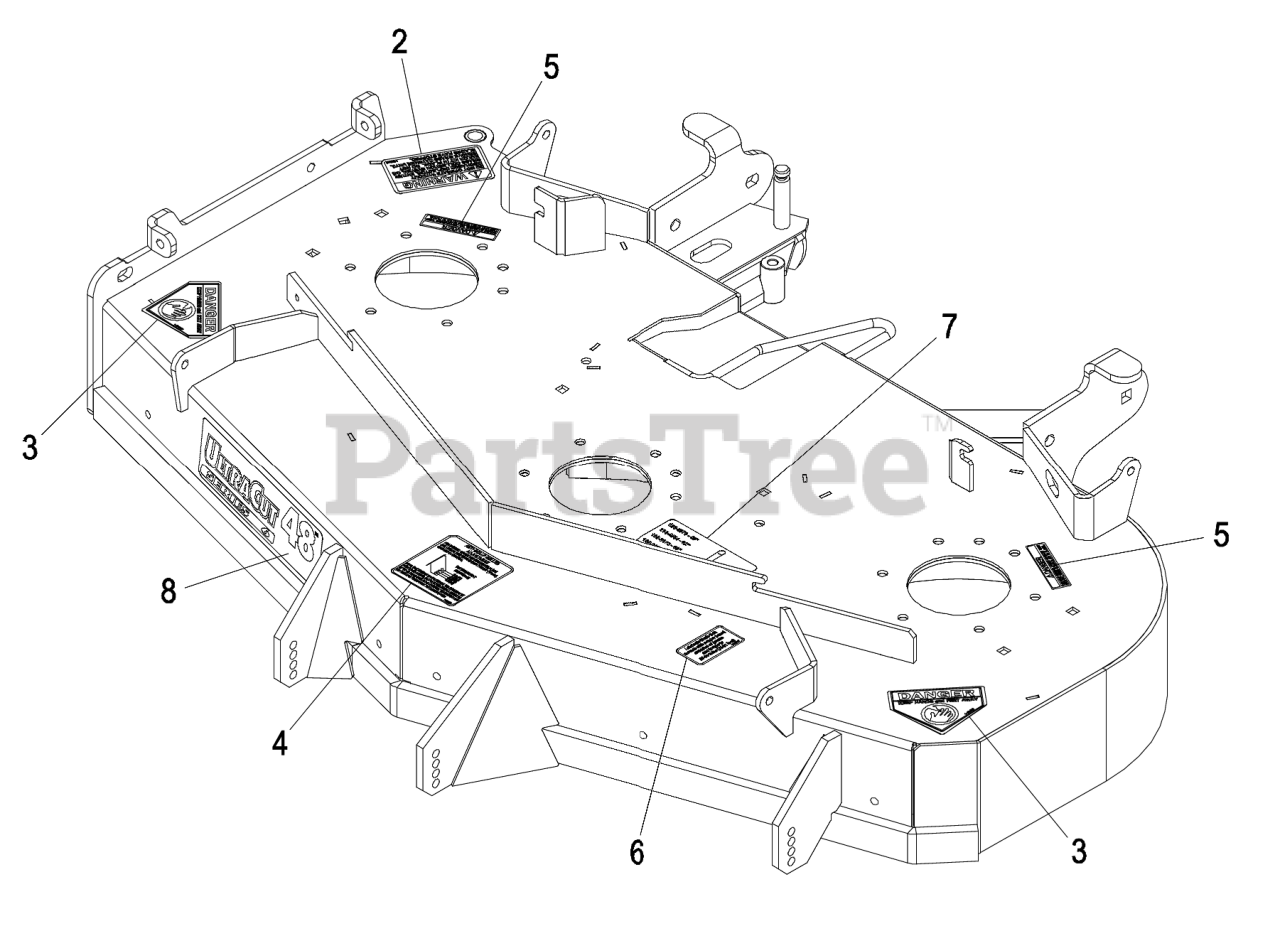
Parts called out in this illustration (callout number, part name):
2	DECAL-WARNING, DISCHARGE
3	DECAL-DANGER
4	DECAL,ANTISCALP
5	DECAL-COVER, MISSING
6	DECAL,BOLT TORQUE
7	DECAL,BELT ROUTING
8	DECAL,ULTRACUT 48 SERIES
